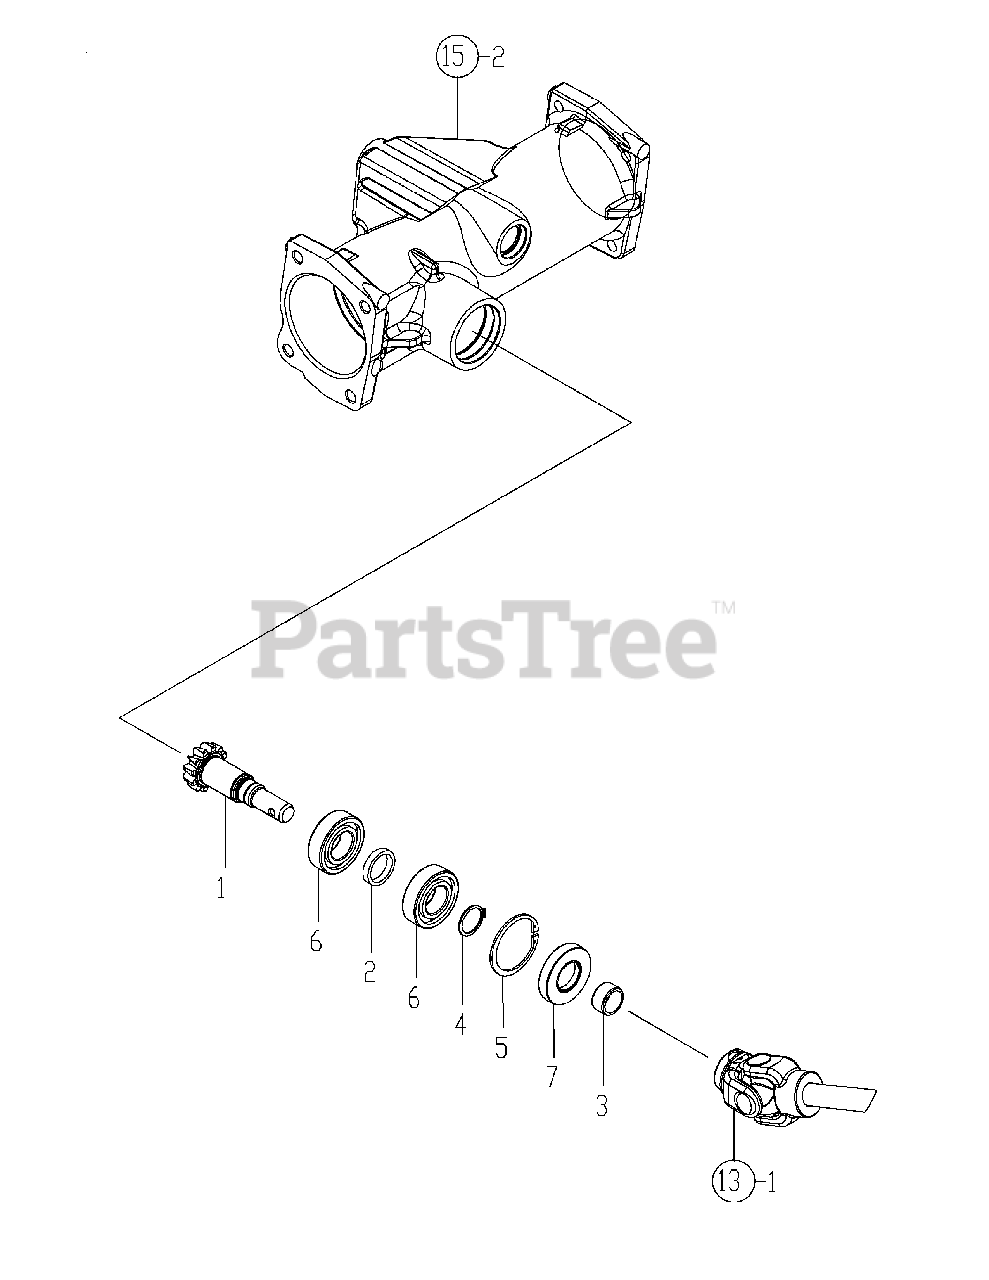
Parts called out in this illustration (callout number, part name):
2	COLLAR 30X25X5.7
3	SLEEVE, 202513
6	BEARING, 6205 NTN
7	SEAL, TC255210
